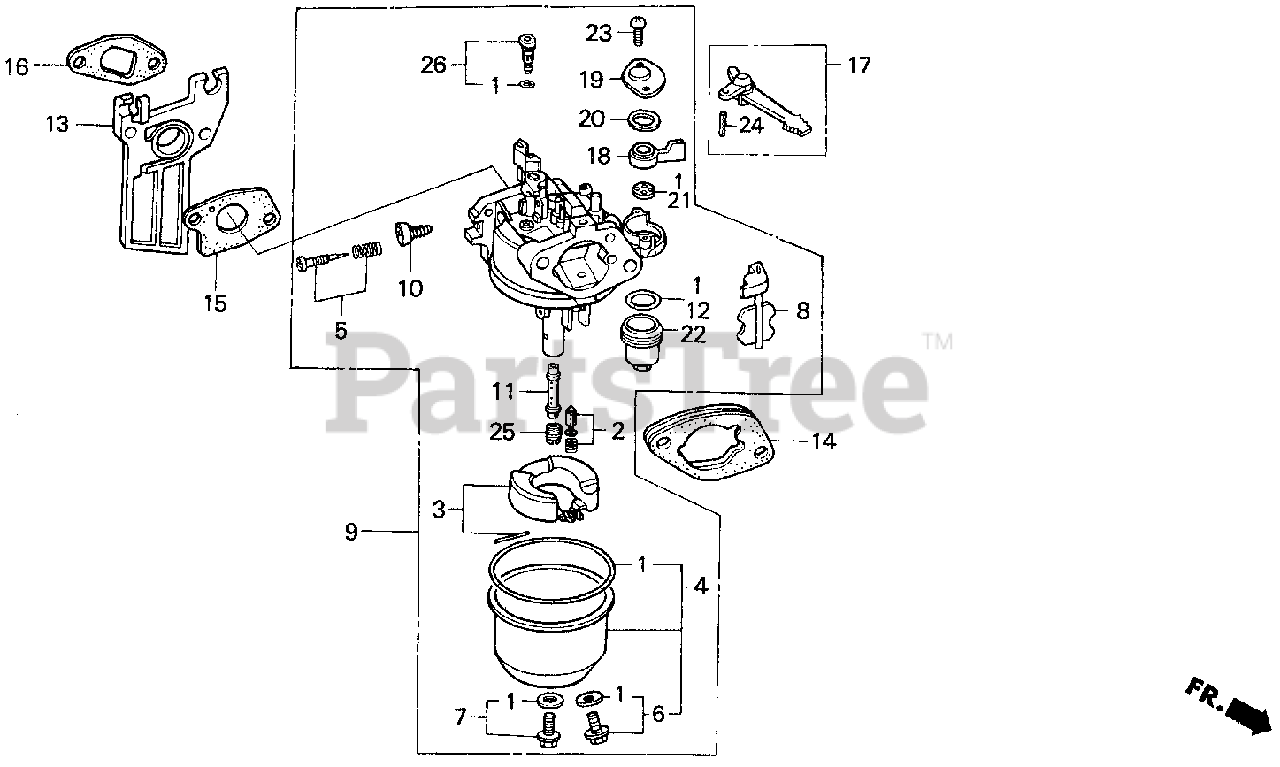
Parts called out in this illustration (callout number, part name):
1	GASKET SET
2	VALVE SET, FLOAT
3	FLOAT SET
4	CHAMBER SET, FLOAT
5	SCREW SET, PILOT
6	SCREW SET, DRAIN
7	SCREW SET B
8	CHOKE SET
9	CARBURETOR ASSY. (BE05B D)
9	CARBURETOR ASSY. (BE05B E)
9	CARBURETOR ASSY. (BE05C B) (W/STRAINER)
9	CARBURETOR ASSY.
10	SCREW, THROTTLE STOP
11	NOZZLE, MAIN
12	GASKET, FUEL STRAINER CUP
13	INSULATOR, CARBURETOR
14	SPACER, CARBURETOR
15	GASKET, CARBURETOR
16	GASKET, INSULATOR
17	LEVER, CHOKE (STD)
18	LEVER, VALVE
19	PLATE, LEVER SETTING
20	SPRING, VALVE LEVER
21	GASKET, VALVE
22	CUP, FUEL STRAINER
23	SCREW, PAN (3X8)
24	PIN, SPRING (2X12)
25	JET, MAIN (#62)
25	JET, MAIN (#65)
25	JET, MAIN (#68)
26	JET SET, PILOT (#35)
